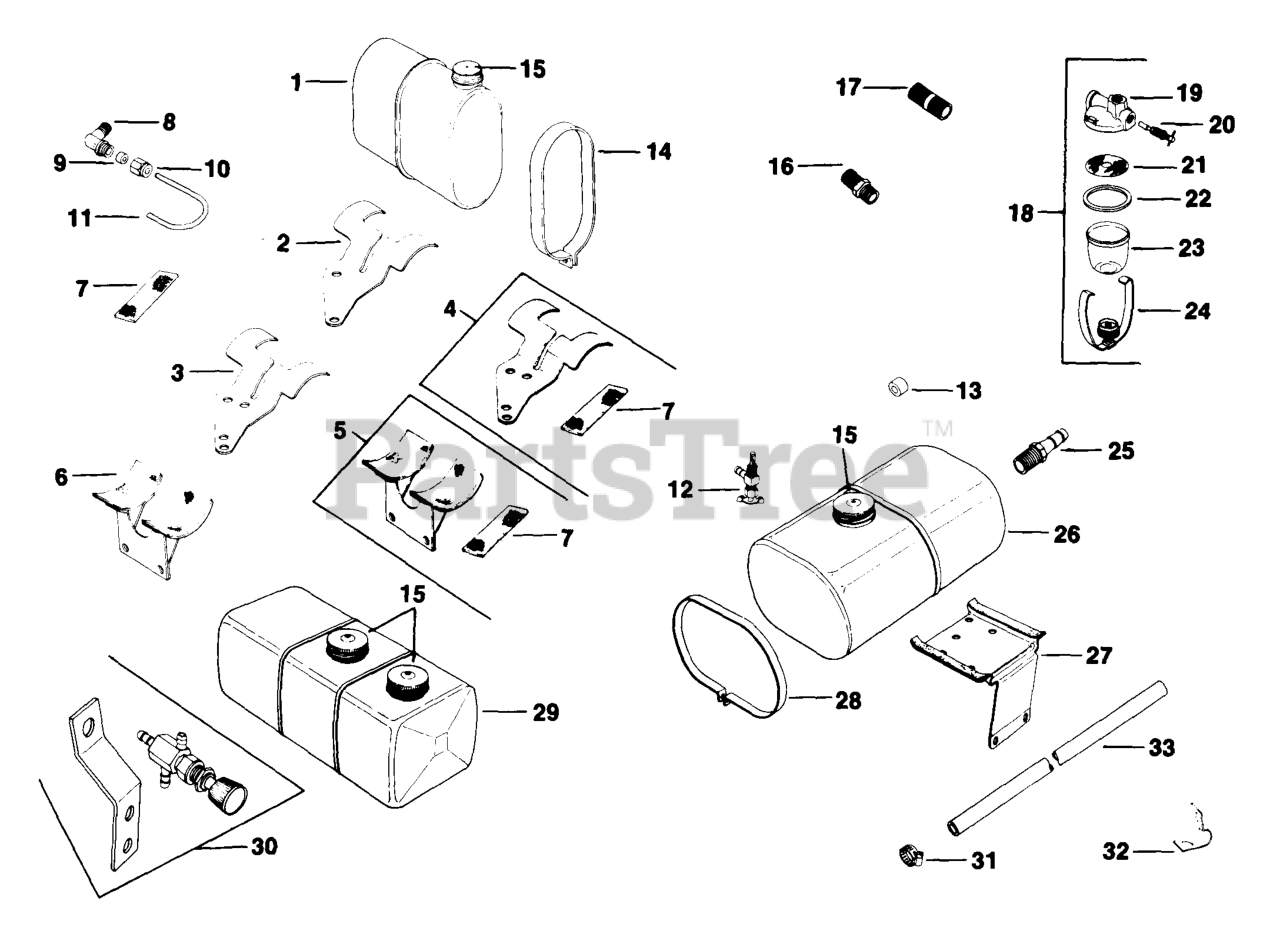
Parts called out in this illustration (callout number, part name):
1	TANK, FUEL USE 47 065 10-S
5	BRACKET
8	ELBOW - (#DSC)
10	NUT - (#DSC)
14	STRAP-DISCONTINUED
17	PIPE - DISCONTINUED
18	KIT - USE 25 755 22
20	VALVE - DISCONTINUED
24	BAIL - DISCONTINUED
